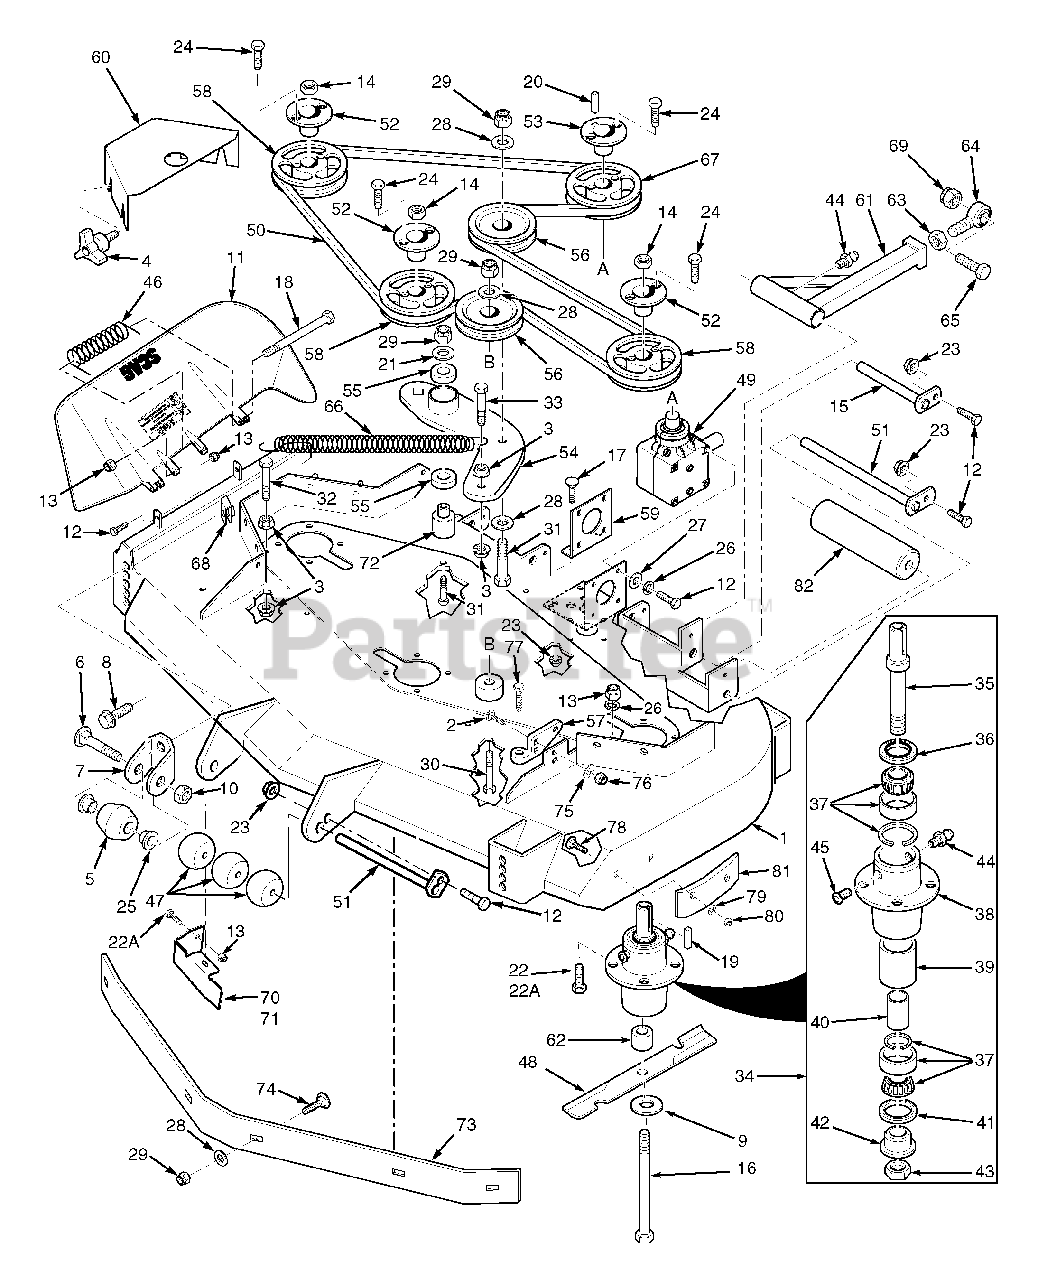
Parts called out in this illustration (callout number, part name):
1	Cutter Deck Advantage
2	Bolt, Carriage 7/16-14 x 1-1/4"
3	Nut, Hex Serrated Flange 3/8-16
4	Wing nut, 3/8-16
5	Anti-Scalp Wheel
6	Bolt, Carriage 3/8-16 x 4"
7	Anti-Scalp Wheel Bracket
8	Bolt, Hex Serrated Flange 3/8-16 x 1"
9	Flatwasher, 5/8" Hardened
10	Locknut, 3/8-16 Center Lock
11	Discharge Chute Advantage - Large
12	Bolt, Hex Head 5/16-18 x 1-3/4" - Front
13	Nut, Hex Elastic Stop 5/16-18 Grade 8
14	Nut, 5/8-11 UNC
15	Push Arm Shaft
16	Bolt, Hex Head 5/8-11 x 9-1/2"
17	Bolt, Carriage 5/16-18 x 3/4"
18	Bolt, Hex Head 5/16-18 x 4-1/2"
19	Key, 1/4 x 1/4 x 2"
20	Key, 1/4 x 1/4 x 1-1/4"
21	Flatwasher,3/8-.39 x .938 x .105 HD
22	Bolt, Hex Head 5/16-18 x 1-3/4"
23	Nut, Hex Serrated Flange 5/16-18
24	Bolt, Hex Head 1/4-20 x 1" Grade 8
25	Bushing, .376 I.D. Oilite
26	Lockwasher, 5/16"
27	Flatwasher, 5/16" (.375 x .875 x .083)
28	Flatwasher, 3/8" (.391 x .938 x .105)
29	Nut, Hex Elastic Stop 3/8-16
30	Bolt, Hex Head 3/8-16 x 3-1/4"
31	Bolt, Hex Head 3/8-16 x 3"
32	Bolt, Hex Head 3/8-16 x 1-1/2"
33	Bolt, Hex Head 3/8-16 x 1-1/2" Grade 8
34	Spindle Assembly
35	Spindle Shaft
36	Seal, Top
37	Bearing Assembly
38	Spindle Housing
39	Spacer, Outside
40	Spacer, Inside
41	Seal, Bottom
42	Spindle Bushing, Bottom
43	Nut, Special 1 - 1/16-18
44	Grease Fitting
45	Relief Fitting, Tapered Spindle
46	Spring, Discharge Chute
47	Wheel, Anti-Scalp
48	Cutter Blade, 21"
49	Gearbox Assembly, Deck Drive
50	Belt, Cutter Deck Drive
51	Roller Shaft
52	Tapered Hub, 1-1/8" Bore
53	Tapered Hub, 1" Bore
54	Idler Arm, Cutter Deck
55	Bearings, Ball
56	Pulley, Idler
57	Lever Assembly, Deck Level
58	Pulley, 6.35 O.D. (61")
59	Mounting Plate, Gearbox
60	Belt, Cover
61	Pusharm
62	Spacer, Spindle Bottom
63	Nut, Hex Head 5/8-18 UNF
64	Rod End, 5/8" Male RH Thread
65	Bolt, Hex Head 5/8-11 x 4-1/2"
66	Spring, Cutter Deck
67	Pulley, 6.75 O.D.
68	U-Nut, 3/8-16
69	Nut, Hex Elastic Stop 5/8-11
71	Discharge Baffle 61V
72	Pivot, Idler - Short
73	Baffle, Custom Cut 61V
74	Bolt, Carriage 3/8-16 x 1"
75	Flatwasher, 7/16-.500 x 1.25 x .083
76	Nut, Elastic Stop 7/16-14
77	Bolt, Deck Adjust
78	Bolt, Carraige 5/16-18 x 3/4"
79	Flatwasher, 5/16"
80	Nut, Center Lock 5/16-18
81	Wear Pad
82	Wheel, Anti-Scalp
